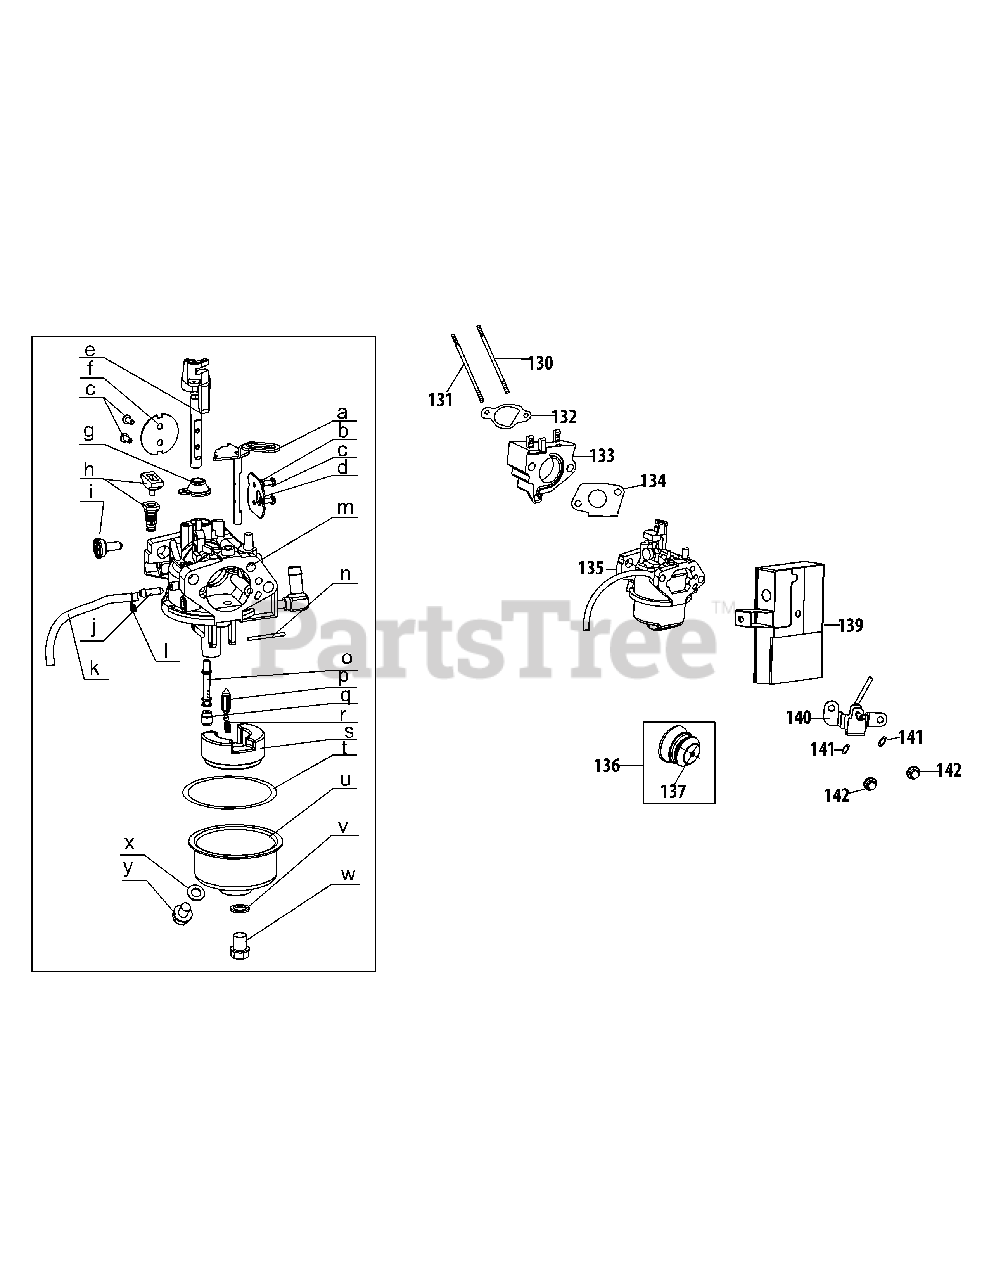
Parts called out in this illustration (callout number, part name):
130	Stud M6-8×100
131	Stud M6-8×118
132	Carburetor Insulator Gasket
133	Carburetor Insulator
134	Carburetor Gasket
135	Carburetor Assembly
136	Primer Assembly
137	Primer Bulb
139	Heater Box
140	Choke Control
141	Lock Washer
142	Nut M6
